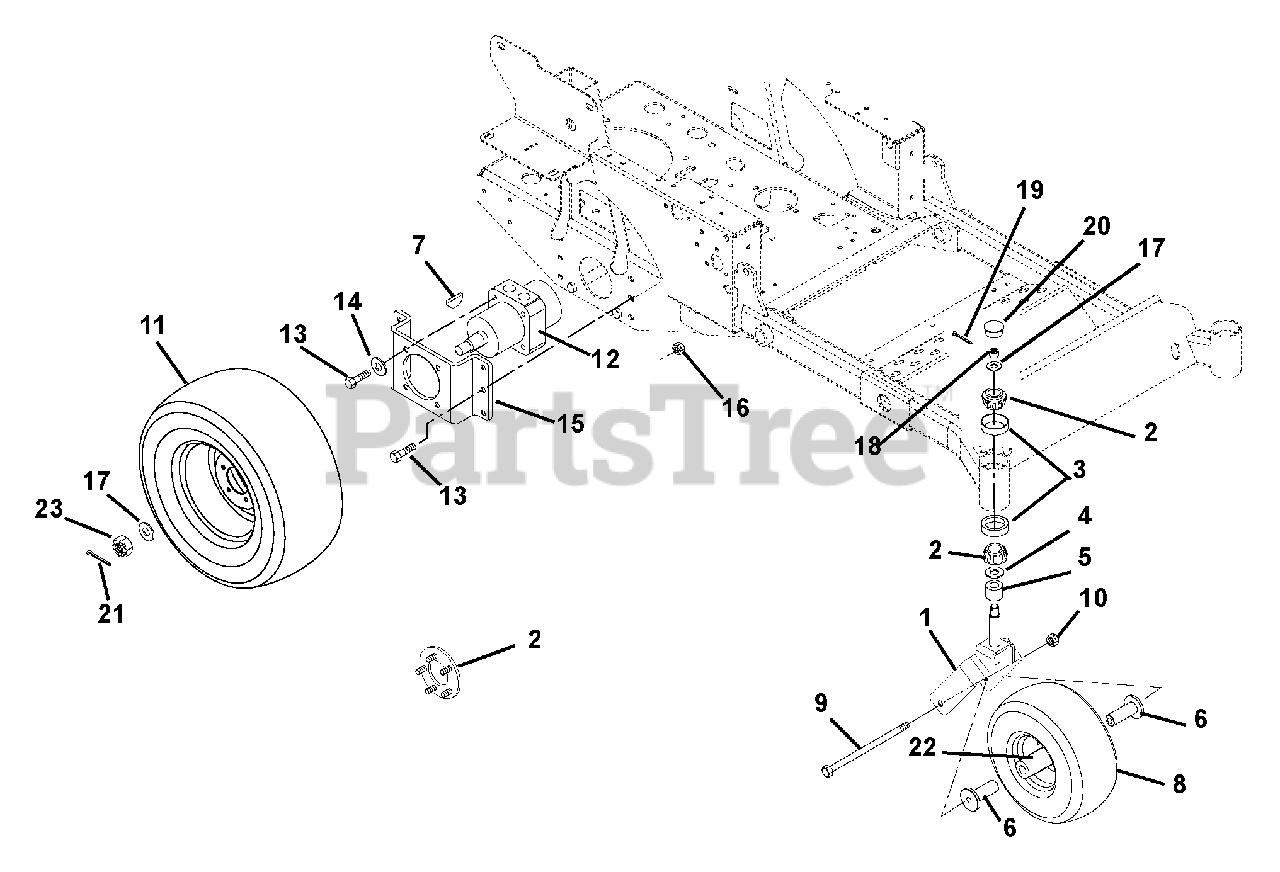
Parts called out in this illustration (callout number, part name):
1	Weldment, Front Fork
2	Bearing, Cone with Grease, 1.0 x .58
3	Bearing, Cup 1.980 x .420
4	Bearing Seal 1.5 x 2 x .18
5	Spacer, PM, 1.03 I.D. x 1.5 O.D. x .375
6	Spacer, Wheel
7	Key, Woodruff .31 x 1.00
8	Wheel/Tire Assembly 5.25 x 13.00
9	Bolt, Hex .50-13 x 7.50 Grade 5
10	Nut, Nyloc Flange .50-13
11	Wheel, Tire Assembly 20 x 10-10 (056, 314)
11	Wheel, Tire Assembly 20 x 10-10 (065)
11	Tire, 20 x 10.00-NHS Turf Saver (065)
11	Tire, 20 x 10.00 Multi Trac C-S (065)
11	Tire, 21 x 7.00 Turf Saver (056, 314)
12	Motor, Hydraulic Wheel
13	Bolt, Hex .38-16 x 1.00 Grade 5
14	Washer, Locking .38 x .094 Regular
15	Bracket, Wheel Motor
16	Nut, Nyloc Flange 3/8-16
17	Washer, Flat Steel .755 x 1.375 x .062
18	Nut, Slotted .75-16
19	Pin, Cotter .16 x 1.00
20	Cap, Dust
21	Pin-Cotter .09 x 1.25 Extended Prong Square Cut
22	Bearing, 25MM I.D. x 52MM OD x 15MM
23	Nut, Hex .75-20
24	Assembly, Service Hub with Studs
